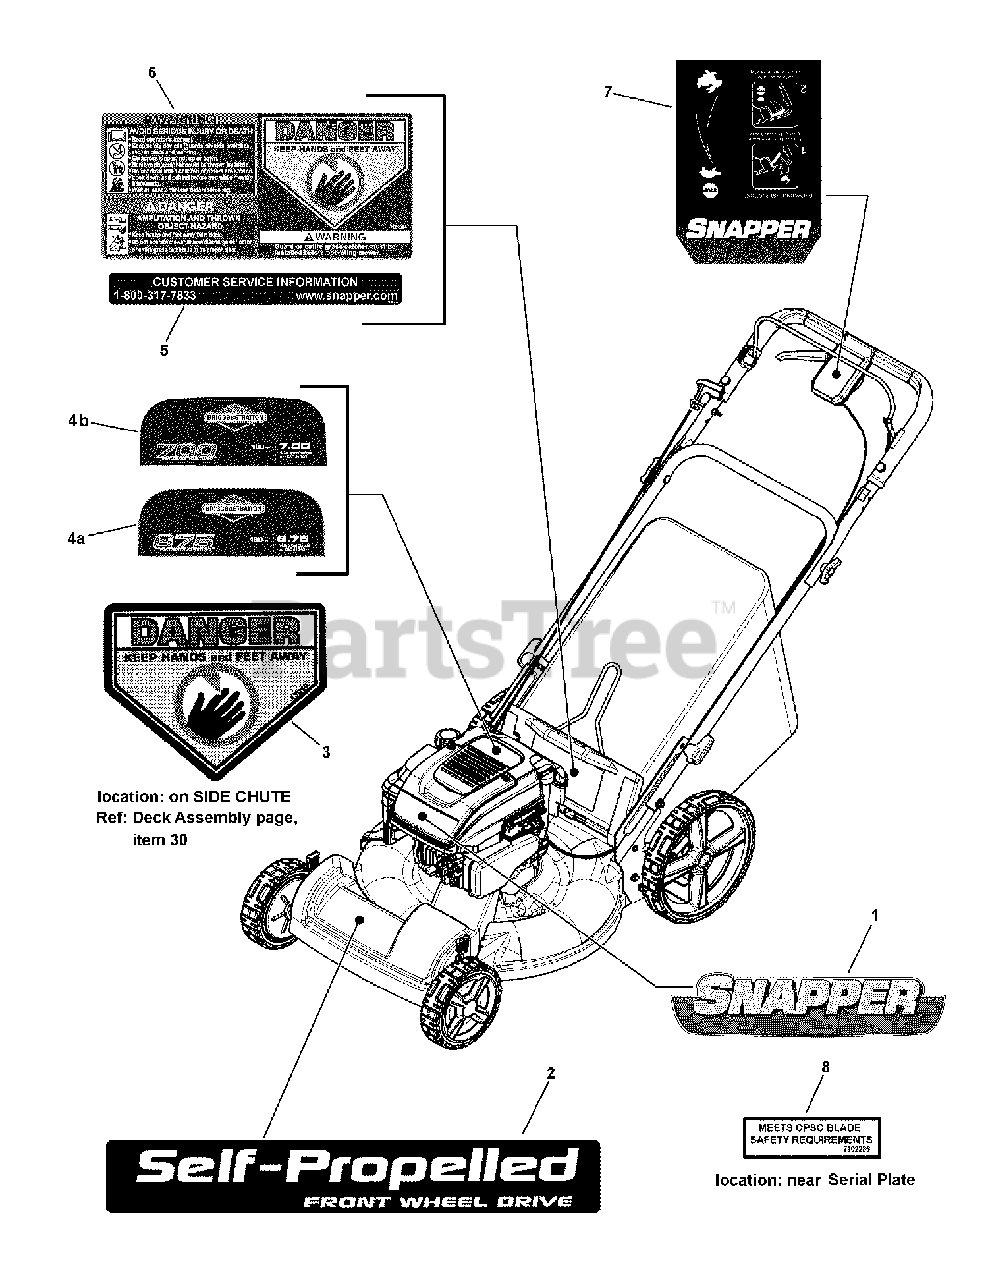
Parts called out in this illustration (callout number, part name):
1	DECAL, Briggs Engine, Snapper
2	DECAL, Front Cover, 22" Snapper, Front Wheel Drive
3	DECAL, Danger, Cut Finger
5	DECAL, Customer Service
6	DECAL, Warning, Rear Discharge Door
7	DECAL, Control Head, VS, Snapper
8	DECAL, CPSC Blade
